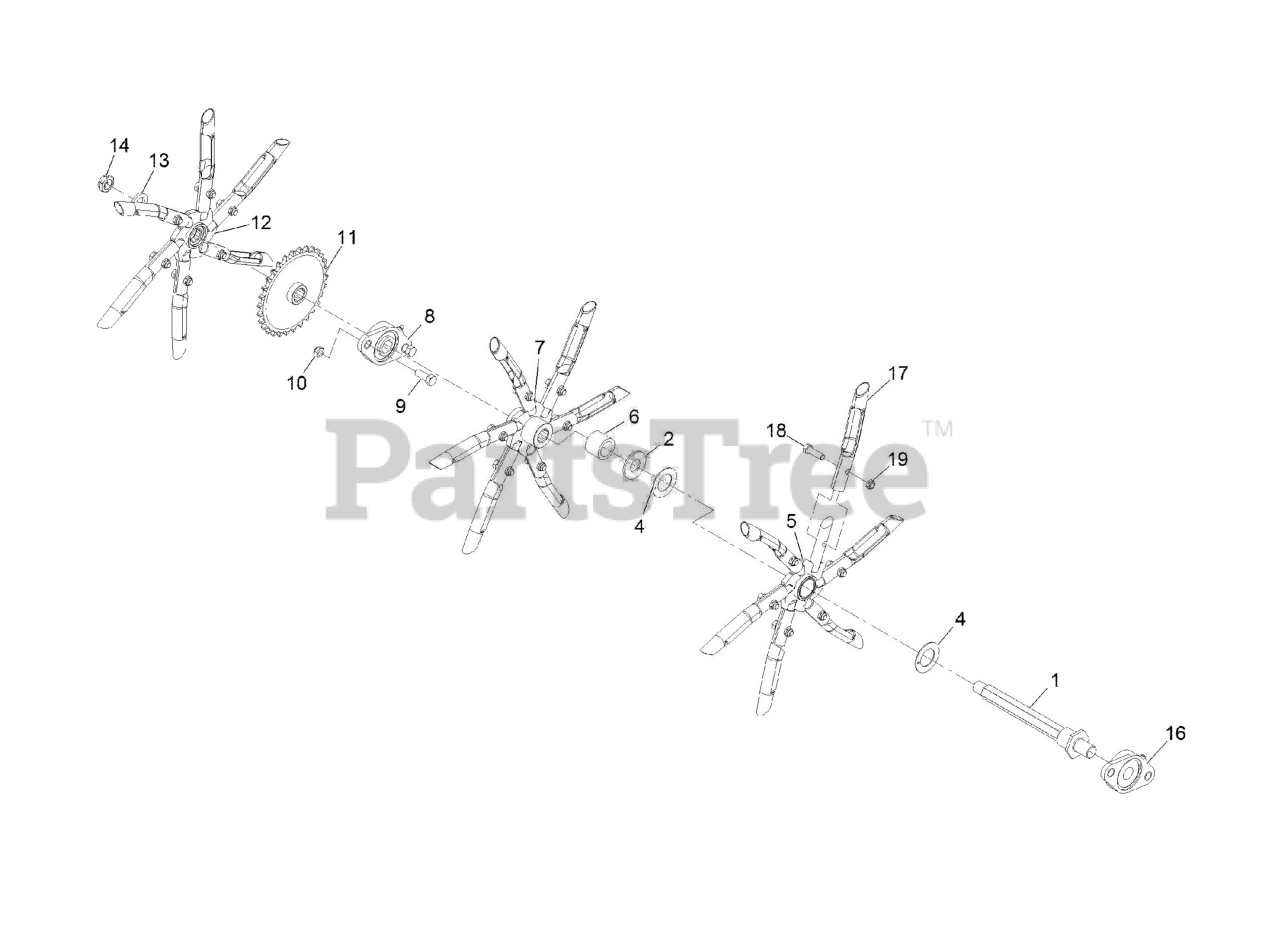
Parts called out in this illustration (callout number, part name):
1	TINE SHAFT ASM
2	KEEPER-TINE, FLOATING
4	WASHER-THRUST
5	FLOATING SPYDER ASM
6	SPACER-TINE
7	DRIVEN SPYDER ASM
8	BEARING-HEX BORE
9	SCREW-HH
10	NUT-LOCK
11	SPROCKET ASM
12	DRIVEN SPYDER ASM
13	WASHER-SPACER
14	NUT-LOCK
16	BEARING-ROUND BORE
17	TINE-CORING (3/4 INCH)
18	SCREW-HH
